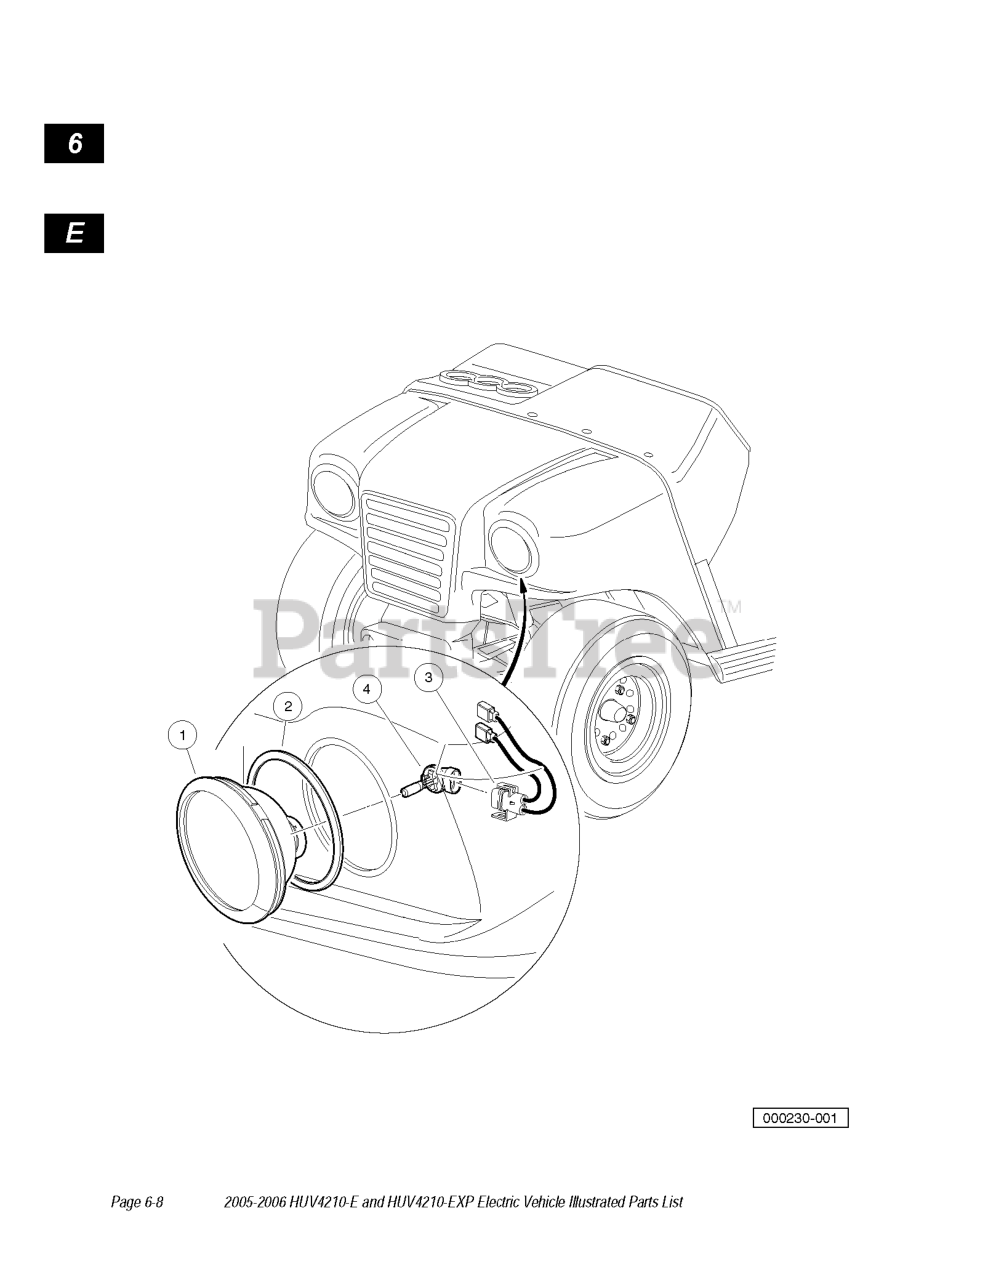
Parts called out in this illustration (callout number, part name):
1	HEADLIGHT ASSY, DRIVER
2	SPACER-HEADLIGHT-OVAL
3	HARNESS-HADLIGHT
4	BULB, HEADLIGHT, OVAL
